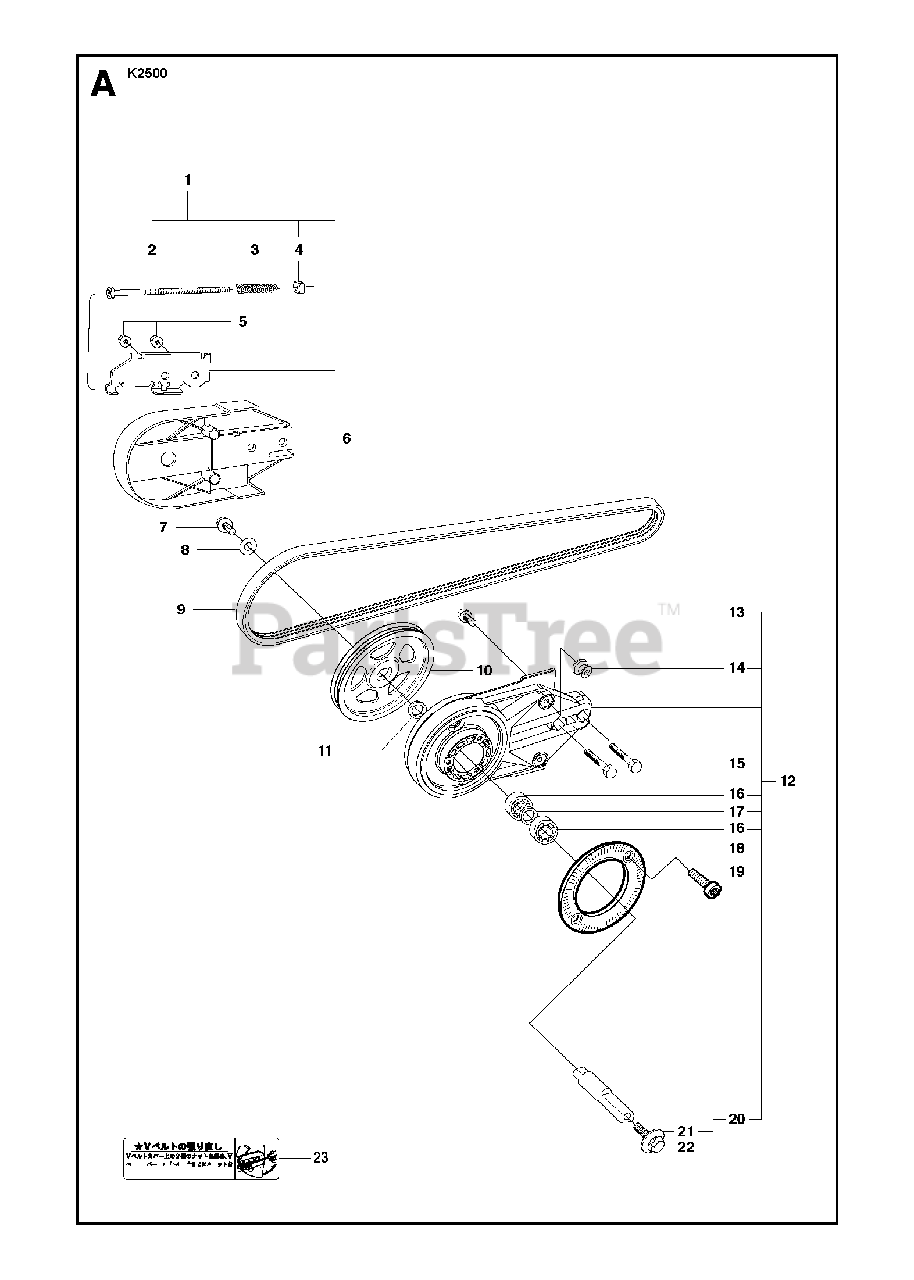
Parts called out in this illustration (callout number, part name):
1	BELT TENSIONER ASSYIncl. 2 - 4 (New Part)
2	SCREW CITXSCMNew Part
12	BEARING HOUSING ASSYIncl. 13 - 20 (New Part)
13	SCREW ITXSCMNew Part
14	TORSION STOPNew Part
16	BALL BEARING
19	SCREW ITXSCMNew Part
23	LABELJapan only (New Part)
